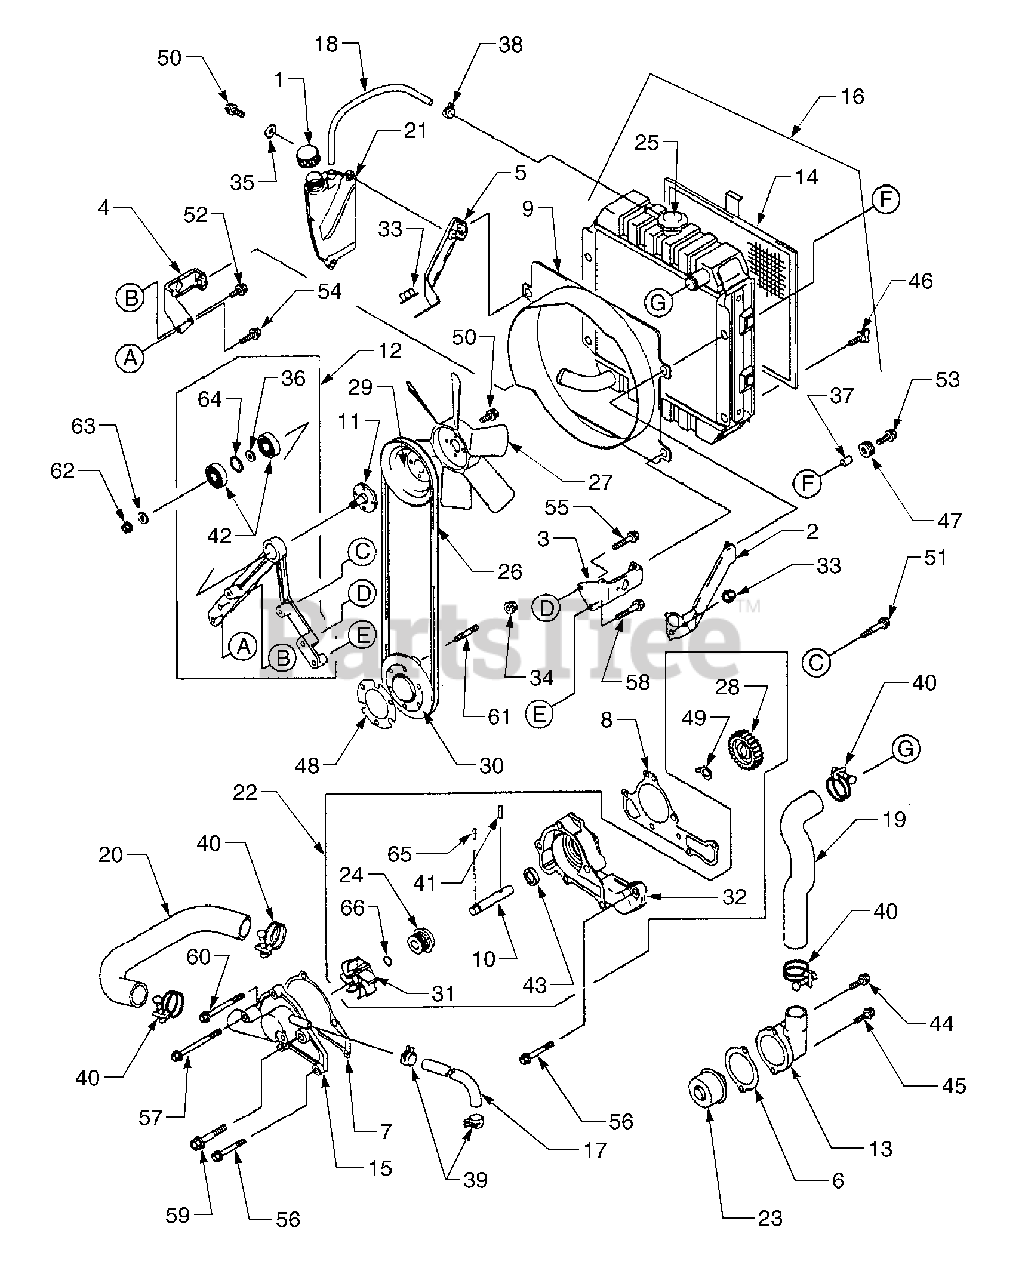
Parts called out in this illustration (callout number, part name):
1	Cap, Reservoir
6	Gasket, Thermostat Cover
7	Gasket, Pump Cover
8	Gasket, Pump Case
10	Shaft, Impeller
11	Shaft, Pulley
12	Housing Assembly
13	Cover, Thermostat
15	Cover, Pump
16	Radiator Assembly
17	Hose, Cooling, 7.5 x 13.5 x 30.5
18	Hose, Cooling, 7.5 x 10.5 x 46
19	Hose, Cooling
20	Hose, Cooling
22	Pump, Water
24	Seal, Mechanical
25	Cap Assembly, Pressure
36	Spacer, 12 x 18 x 1.4
42	Bearing, Ball
44	Bolt, .6 x 40
45	Bolt, .6 x 20
48	Shim, 0.6 Thk
50	Bolt, Flanged, 6 x 16
51	Bolt, Flanged, 6 x 35
52	Bolt, Flanged, 8 x 20
53	Bolt, Flanged, 8 x 25
54	Bolt, Flanged, 8 x 30
55	Bolt, Flanged, 8 x 40
56	Bolt, Flanged, 6 x 45
57	Bolt, Flanged, 6 x 75
58	Bolt, Flanged, 8 x 45
59	Bolt, Flanged, 8 x 70
60	Bolt, Flanged, 6 x 65
62	Nut, Hex Fine
63	Washer, Plain
